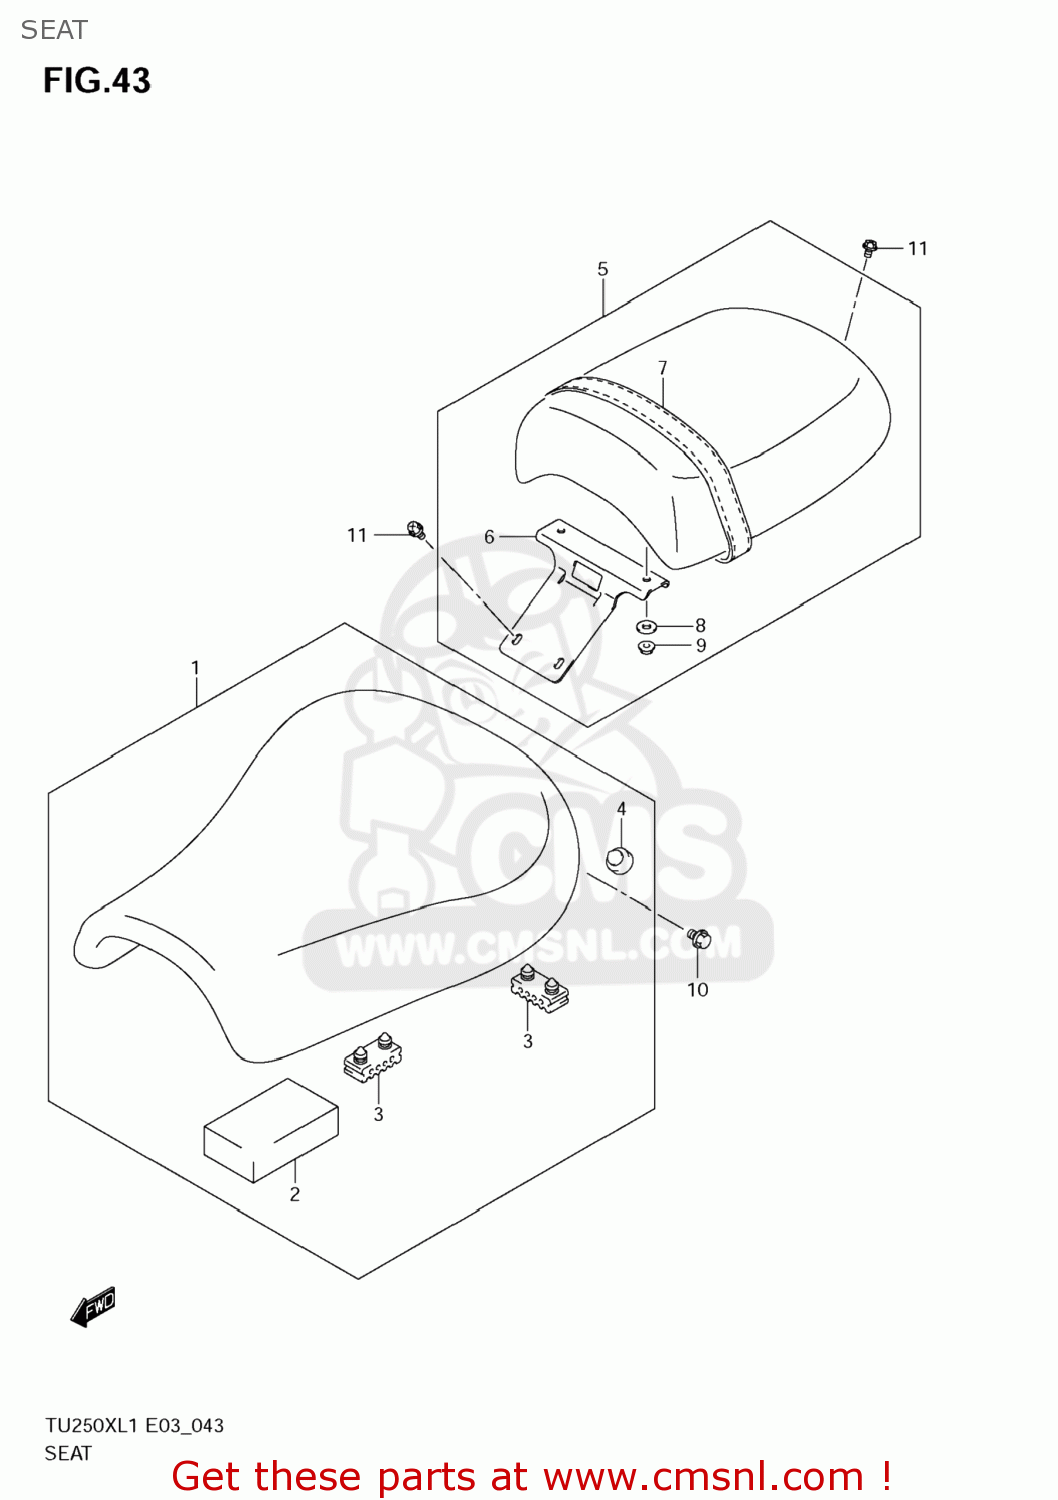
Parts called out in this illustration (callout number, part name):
1	SEAT ASSY
2	CUSHION,TOOL
3	CUSHION,SEAT(40X20X15)
4	CUSHION
5	SEAT ASSY,PILLION
6	PLATE,PILLION SEAT FR
7	BAND,PILLION SEAT GRIP
8	WASHER(6.5X18X1.6)
9	NUT
10	BOLT
11	SCREW
